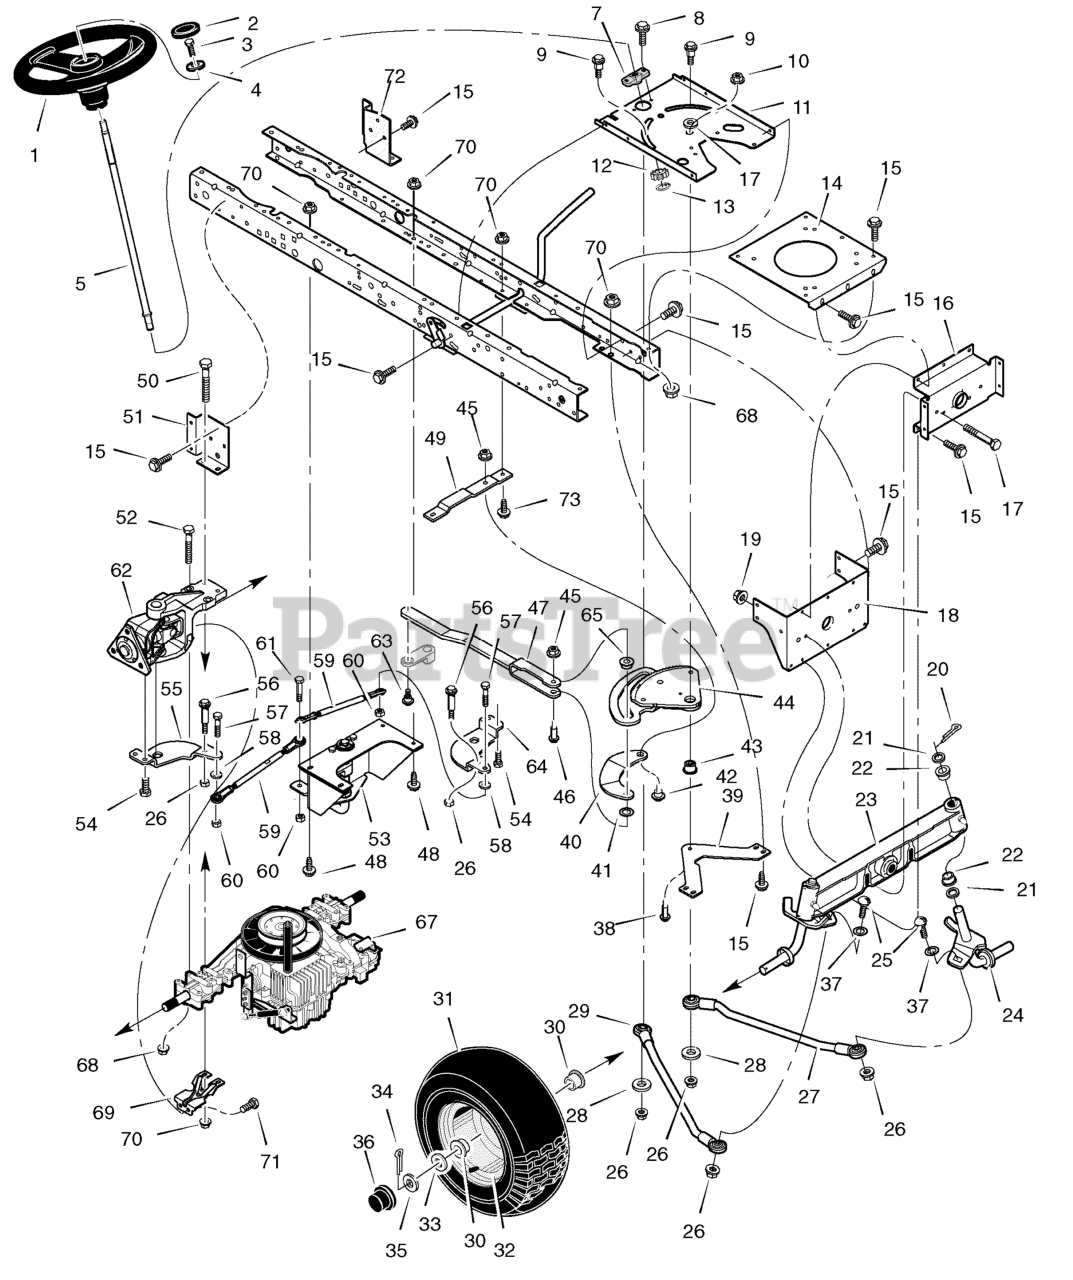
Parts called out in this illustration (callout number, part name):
1	Wheel, Steering
2	Cap, Steering Wheel
3	Screw, Hex
4	Washer
5	Shaft, Steering
7	Bearing, Lower Steering
8	Screw
9	Bolt, Shoulder
10	Nut, Flanged Lock
11	Plate, Steering
12	Gear, Pinion
13	Ring, Snap
14	Plate, Engine
15	Screw
16	Hanger, Axle
17	Bolt, Hex
18	Bracket, Rear Hanger
19	Nut, Flanged Lock
20	Pin, Cotter
21	Washer
22	Bearing, Steering
23	Axle, Front
24	Spindle Assembly, Left
25	Bolt, Carriage
26	Nut, Flanged Lock
27	Link, Left Drag
29	Link, Right Drag
30	Bearing, Front Wheel
31	Tire ONLY *
32	Wheel and Tire Assembly
33	Washer
34	Pin, Cotter
35	Washer
36	Hub Cap
37	Washer
38	Bolt, Hex
39	Support, Sector Gear
40	Follower, Cam
41	Washer
42	Bolt, Shoulder
43	Bearing, Sector Gear
44	Sector Gear & Cam Assembly
45	Nut. Flanged Lock
46	Bolt, Shoulder
47	Link, Primary Drag
48	Screw
49	Member, Cam Cross
50	Bolt, Hex
51	Bracket, Right Transaxle
52	Bolt, Shoulder
53	Pivot Assembly, Rear
54	Screw
55	Arm, Right Rear
56	Bolt, Shoulder
57	Bolt, Hex
58	Washer, Split Lock
59	Rod Assembly, Tie
60	Nut, Lock
61	Bolt, Hex
62	Steering Assembly, Rear
63	Bolt, Shoulder
64	Arm, Left Rear
65	Bushing, Cam
67	Transaxle
68	Nut, Flanged Lock
69	Bracket, Transaxle Support
70	Locknut, Flange
71	Screw
72	Bracket, Left Transaxle
73	Screw
